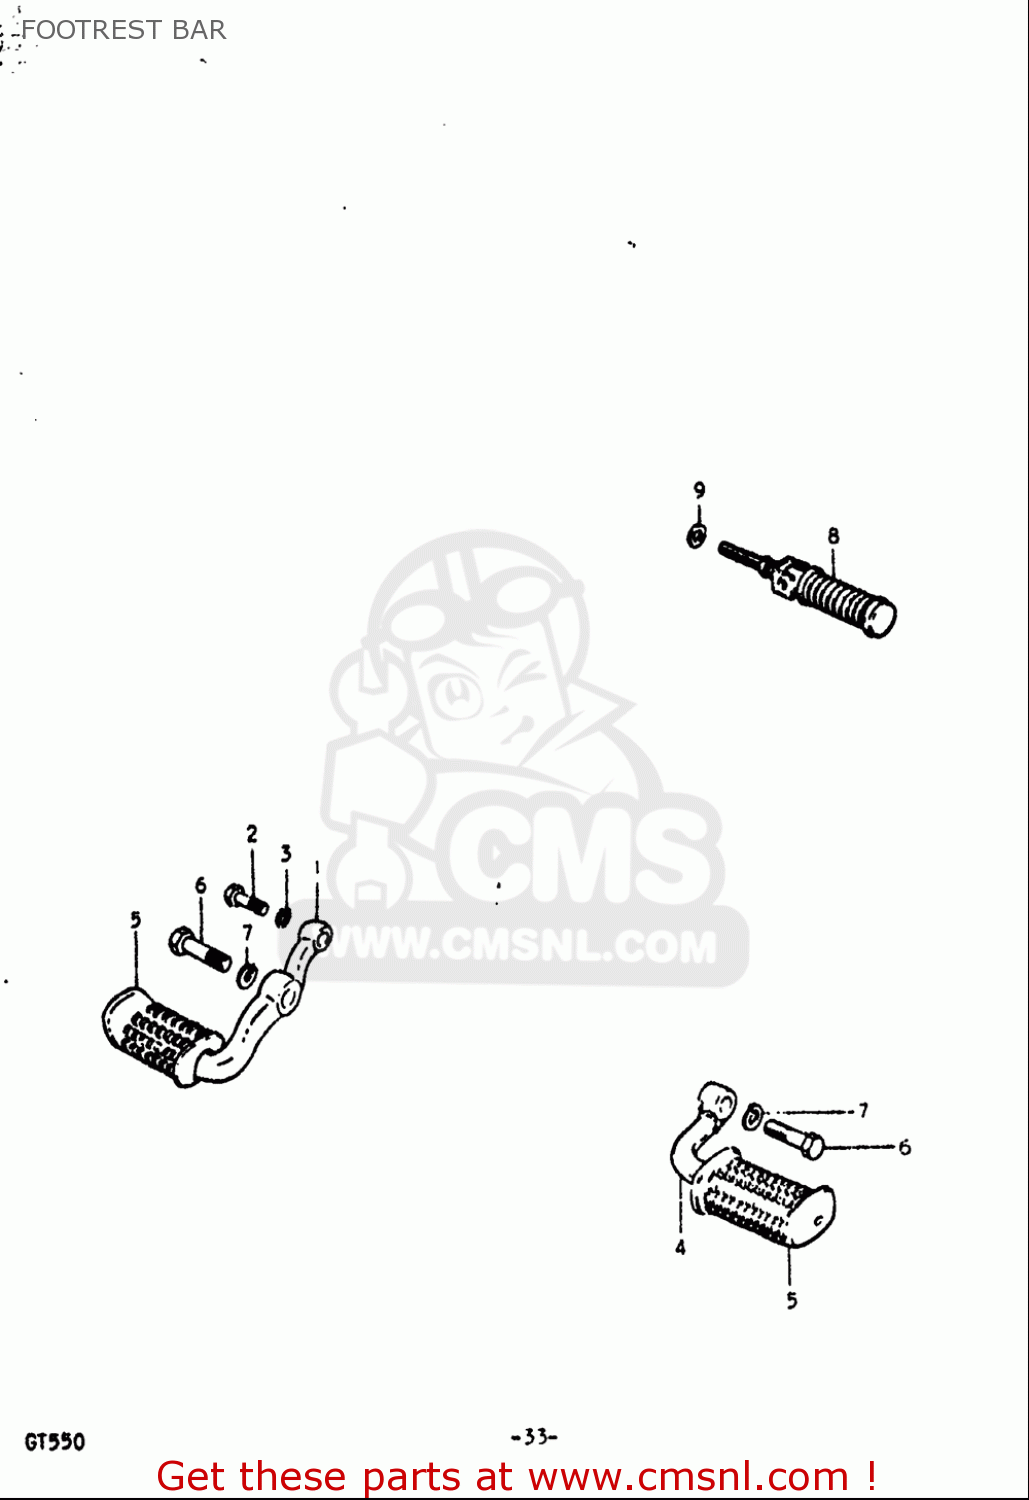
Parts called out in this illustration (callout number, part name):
2	BOLT
3	WASHER,LOCK
6	BOLT
7	WASHER,LOCK
8	FOOTREST ASSY,PILLION
9	WASHER
